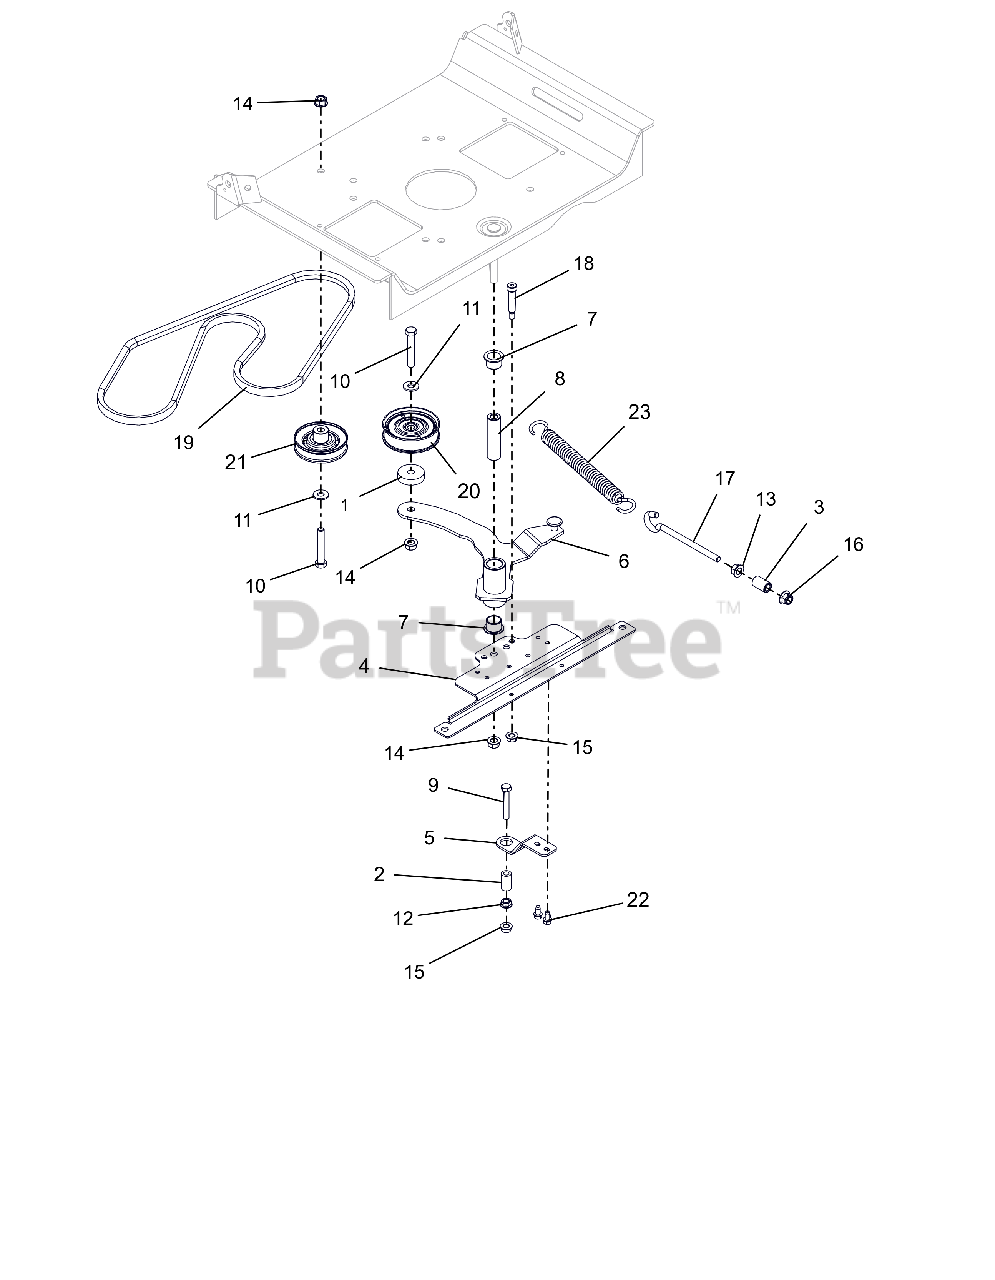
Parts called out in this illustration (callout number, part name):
1	SPACER, .39 X 1.50 X .380
2	SPACER, RUBBER 5/16 IDX1.0 LG
3	SPACER, .375X.625X.970 (PM)
4	BRKT, DRIVE IDLER MOUNTING
5	BRKT, CLUTCH STOP (XL)
6	WLDMT,GRD DRIVE IDLER ARM-LGR
7	BSHG-FLG 0.75X0.875X.625X1.125
8	BUSHING, SLEEVE .38X.750X2.78
9	@BLT-HEX .31-18X2.00 GR5 YWZC
10	@BLT-HEX .38-16X2.25 GR5 YWZC
11	@WSHR-FL-STL.38X.875X.083 YWZC
12	@NUT-SPNLK-FLG .312-18 YWZC
13	@NUT-SPNLK-FLG .375-16 YWZC
14	@NUT-LK-TOP-FLG .38-16 YWZC
15	@NUT-LK-TOP-FLG .31-18 YWZC
16	@NUT-LK-NYL-FLG .38-16 YWZC
17	BOLT,.38-16 X 4.25-.62 DIA EYE
18	BLT-SHLDR .38X1.5X.31-18 SLT Y
19	V-BELT, A-RAW EDGE
20	IDLER, FLAT - 3.05" X .75"
21	IDLER, V-3.000 OD
22	SCR-TAP .25-20X.50 HWH TR YWZ
23	SPRING, EXTENSION
